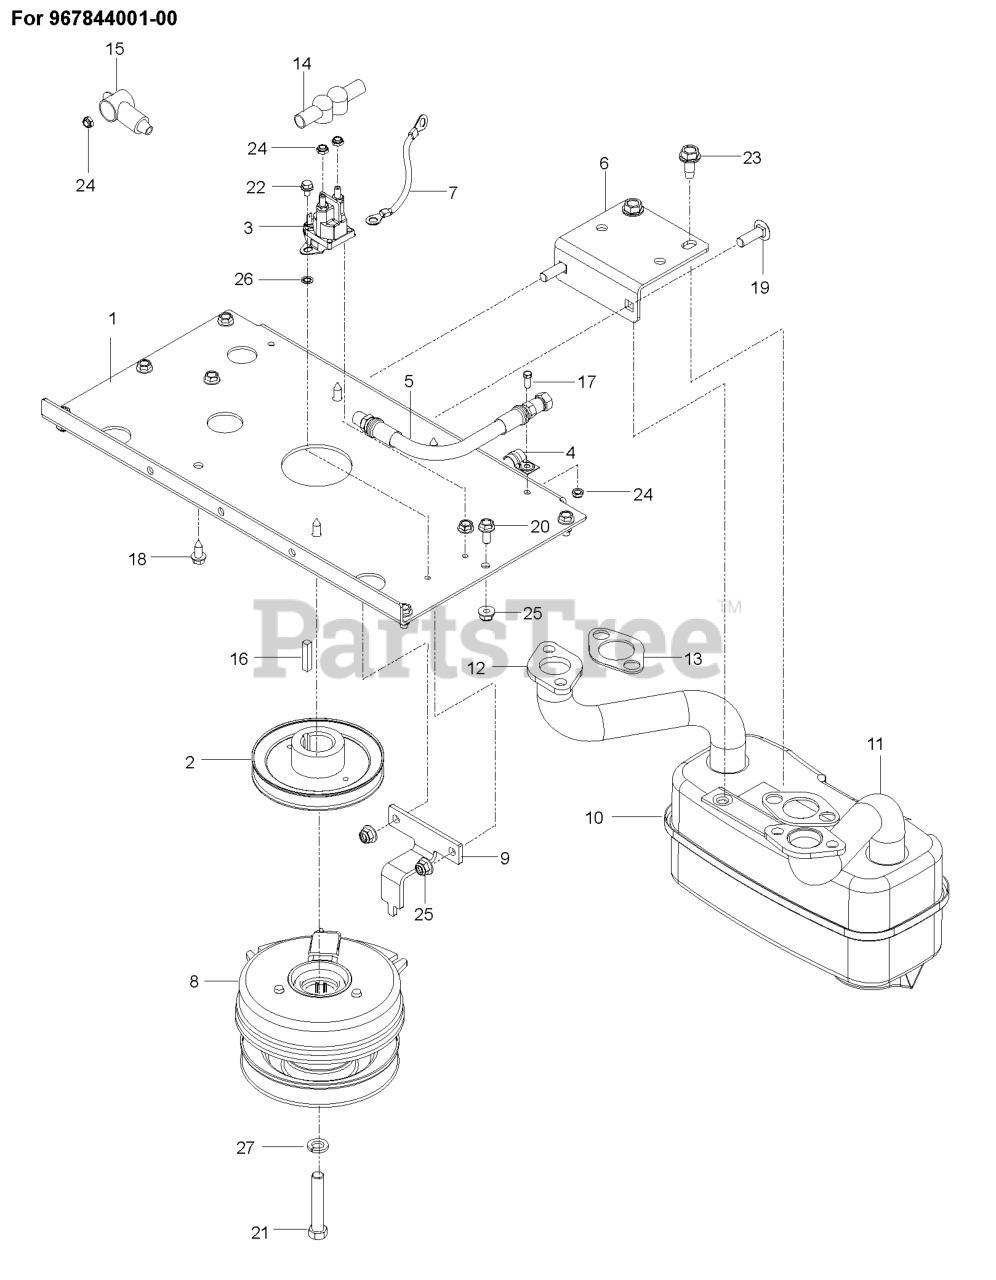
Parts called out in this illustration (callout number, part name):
1	PLATE.PNT.ENGINE.E-DIP
2	PULLEY, V, 1.125 BORE
3	SOLENOID.STARTER.BRASS.PLUNGER
5	HOSE.ASSEMBLY.OIL.DRAIN
6	BRKT, MUFFLER, BLK
7	CABLE POSITIVE
8	CLUTCH 200 FT LB
9	STOP, CLUTCH
10	MUFFLER ASM TWIN
11	PIPE.EXHAUST.LH.CV18/20
12	PIPE.EXHAUST.RH.CV18/20
13	GASKET.EXHAUST.KAWASAKI
14	TERMINAL COVER
16	KEY, 1/4 SQ X 1 1/4
17	HCS 1/4-20.
18	SCREW 3/8-16X1
19	RHSSNB 5/16C X 1.0
20	HHFS 5/16-18 X 3/4
21	CLUTCH BOLT7/16-20X2.5 GR596HR
22	HWST 1/4C X 3/8
23	BOLT 5/16-18 X 3/4
24	JAM NUT 1/4C (2 2 PW01)
25	5/16-18 NYLOC FLANGE NUT
26	WASHER 1/4 INT TOOTH
27	WASHER 7/16 LOCK
